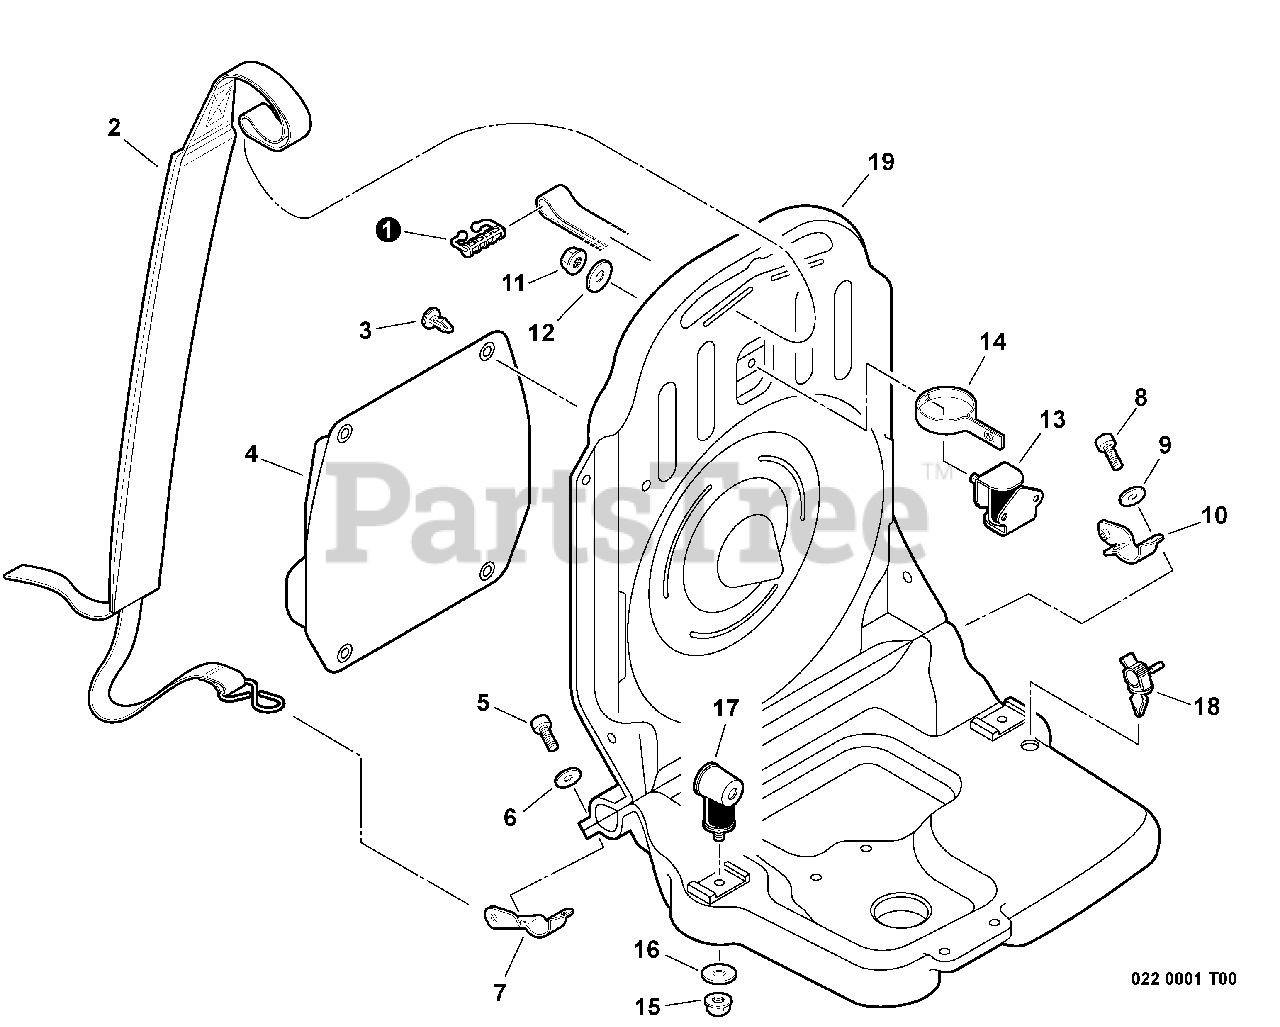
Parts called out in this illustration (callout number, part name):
1	CLIP, HARNESS
2	HARNESS ASSY, BACKPACK
4	CUSHION, BACKPACK
5	BOLT 5×20
6	WASHER 5.5×16×2T
7	CONNECTOR, HARNESS (A)
8	BOLT 5×20
9	WASHER 5.5×16×2T
10	CONNECTOR, HARNESS (B)
11	NUT, FLANGE M5
12	WASHER 5.5×16×2T
14	RETAINER
15	NUT, FLANGE M5
16	WASHER 5.5×16×2T
17	CUSHION, FRAME 5
18	CLIP, CABLE
19	FRAME, BACKPACK
